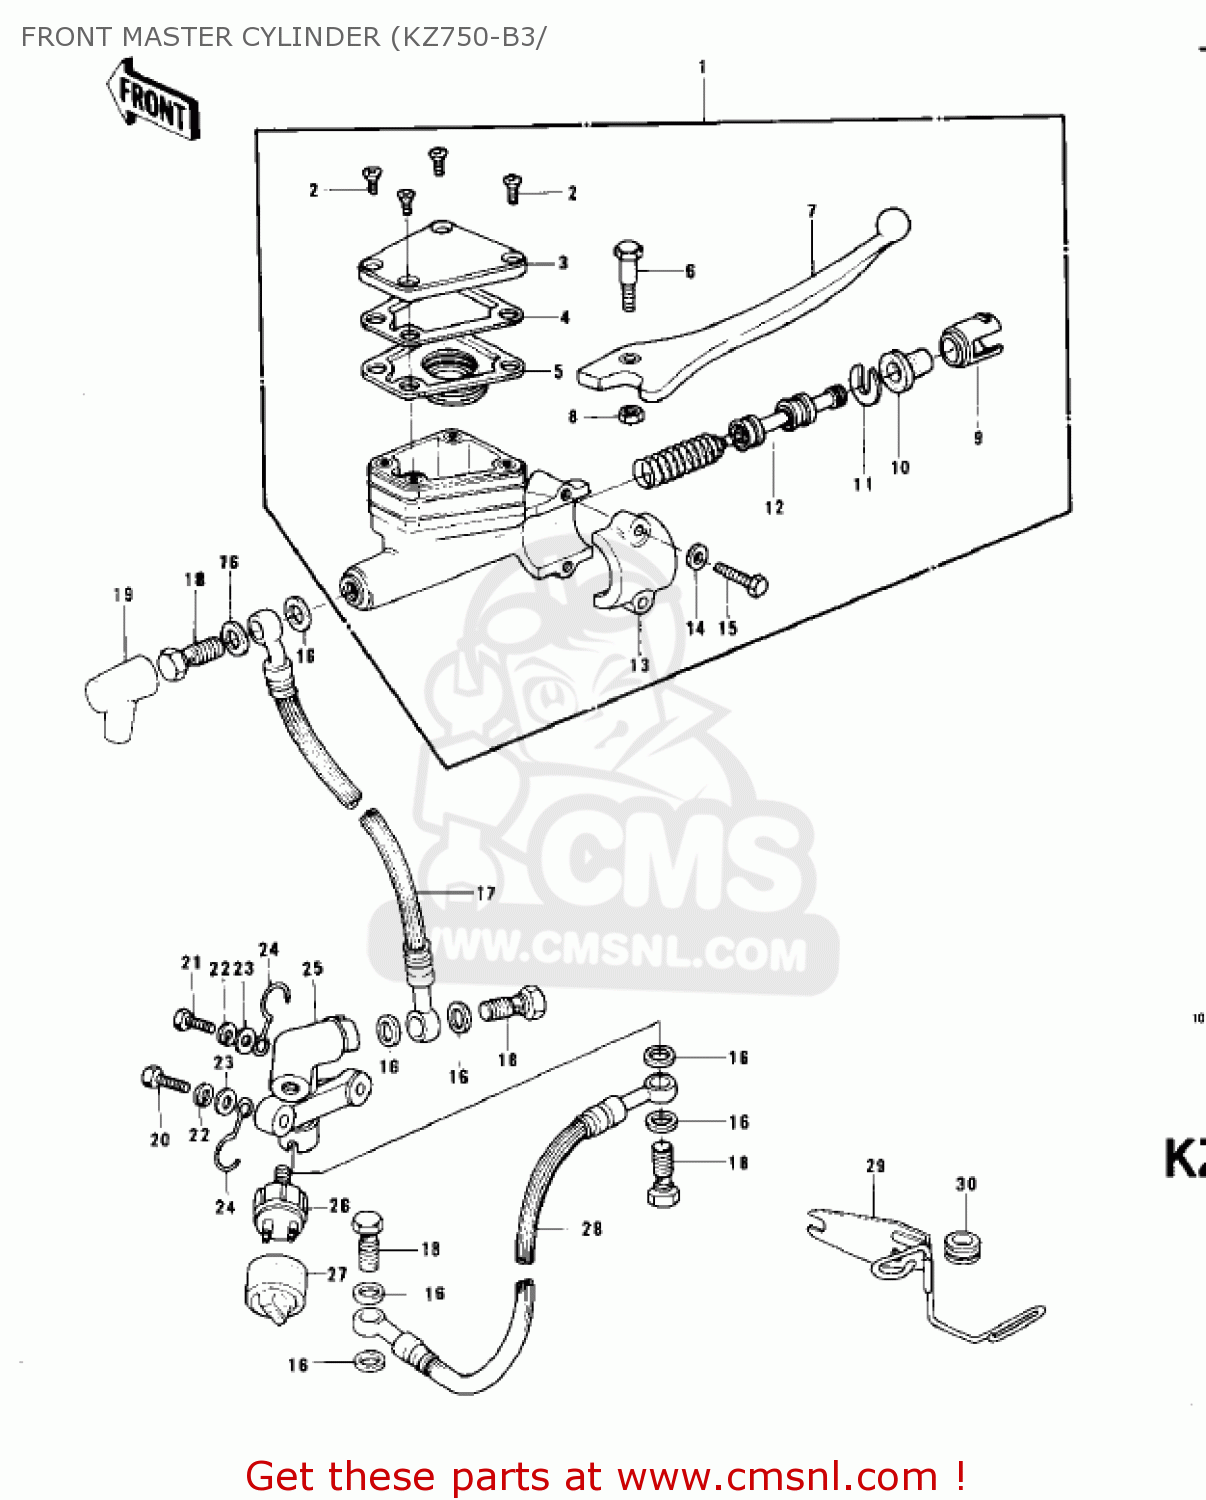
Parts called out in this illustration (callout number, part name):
1	CYLINDER ASSY,MASTER
2	SCREW,COUNTERSUNK HED
3	CAP-BRAKE
4	PLATE-DIAPHRAGM
5	DIAPHRAGM
6	BOLT, CLUTCH LEV FITT
7	LEVER-GRIP,FRONT BRAK
8	NUT,6MM
9	LINER,PISTON
10	COVER-SEAL,BRAKE PIST
11	STOPPER-BRAKE,PISTON
12	PISTON-COMP-BRAKE
13	HOLDER-BRAKE,MASTER C
14	WASHER-PLAIN,6MM
15	BOLT-HEX HEAD,6X25
16	WASHER,10.5X15X1.5
17	HOSE-BRAKE
18	BOLT,OIL,L=23
19	BOOT,DUST
20	BOLT,6X32
21	BOLT,6X22
22	WASHER-SPRING,6MM
23	WASHER-PLAIN,6MM
24	CLAMP,CABLE
25	JOINT-THREE WAY
26	SWITCH,BRAKE,FR
27	CAP,FRONT BRK SWITCH
28	HOSE-BRAKE,L=464
29	BRACKET,BRAKE HOSE,LH
30	GROMMET,BRAKE HOSE
